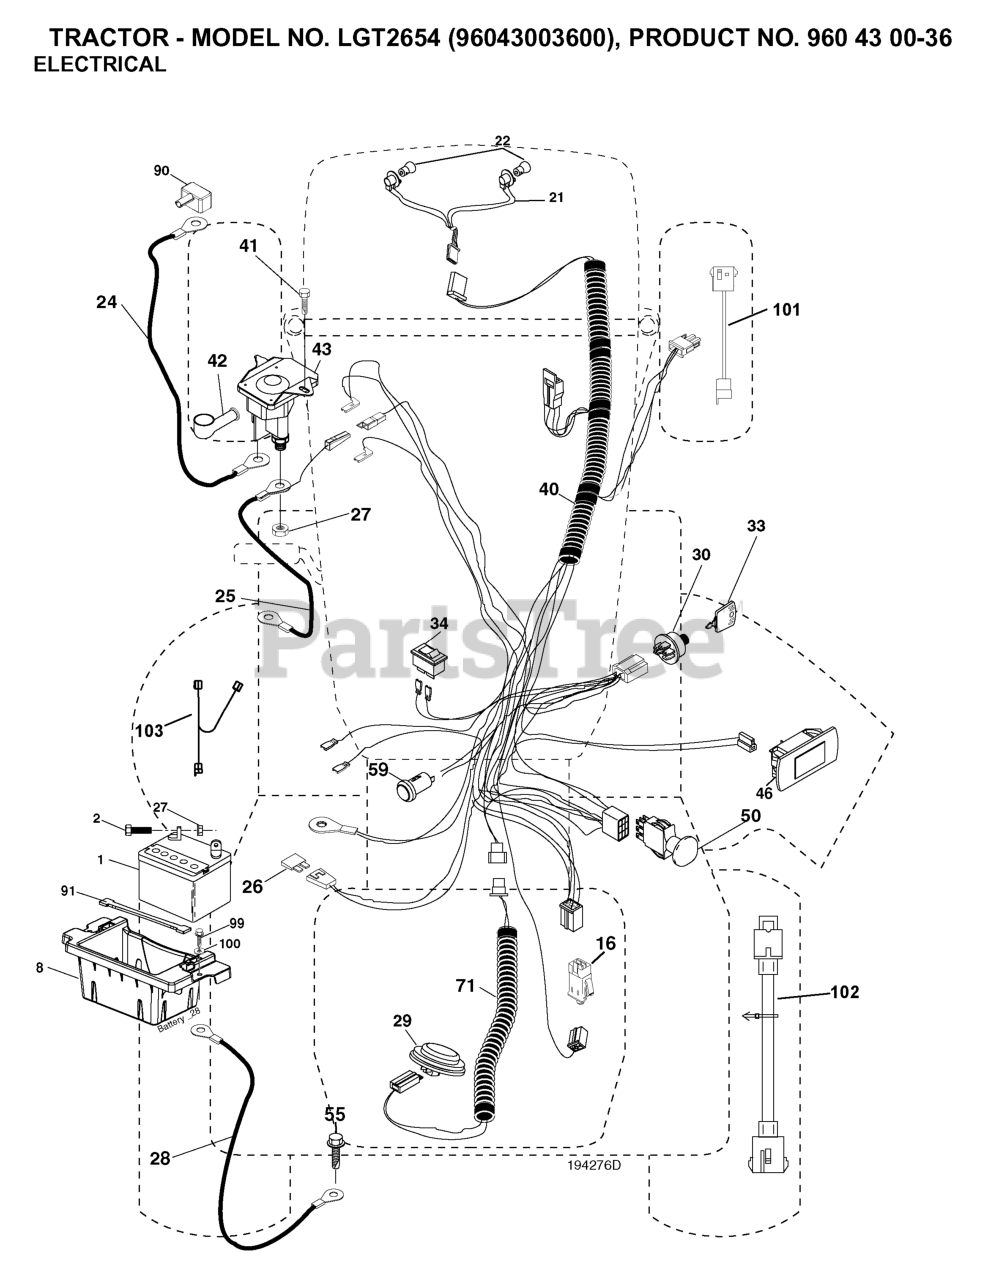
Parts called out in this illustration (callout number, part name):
1	BATTERY 12V .35 AMP
2	BOLT.HEX.1/4.X.3/4.DICHROMATE
8	BOX.BATTERY.MOUNT.FRONT.LT
16	SWITCH INTERLOOK PUSH-IN
21	HARNESS ASSY LIGHT
24	CABLE.BATT.POS.WIRE.TG.DA SOL
25	CABLE.START.RED.17.5".
26	FUSE 20AMP
27	NUT
28	CABLE GROUND 6 GA 21" 90T BLK
29	SWITCH.SEAT.DELTA.OPC.
30	SWITCH.IGN.DELTA.W.LGH.ROS
33	KEY MLD GEN DELTA
40	HARNESS.IGN.DASH.HUQ/P
41	SCREW
42	TERMINAL COVER
43	SOLENOID.W/BRASS.PLUNGER
46	RP.GUAGE.SRVCMNDR.HRMTR.
50	RP.PTO.SWITCH.8 TERMINAL.BLACK
55	SCREW.THDROL.5/16-18X3/4.TTY
59	OUTLET.12-VOLT
71	HARNESS-CHASSIS SUB
90	COVER.TERMINAL.BATTERY
91	STRAP.BATTERY.MOUNT.FRONT(2 2)
99	SCREW HEXWSHR 1/4-20X3/4
101	PIGTAIL.MATNLK.NEW.HAR
102	HARNESS PIGTAIL PCH TEX ROS
103	HARNESS PIGTAIL 12V OUTLET
